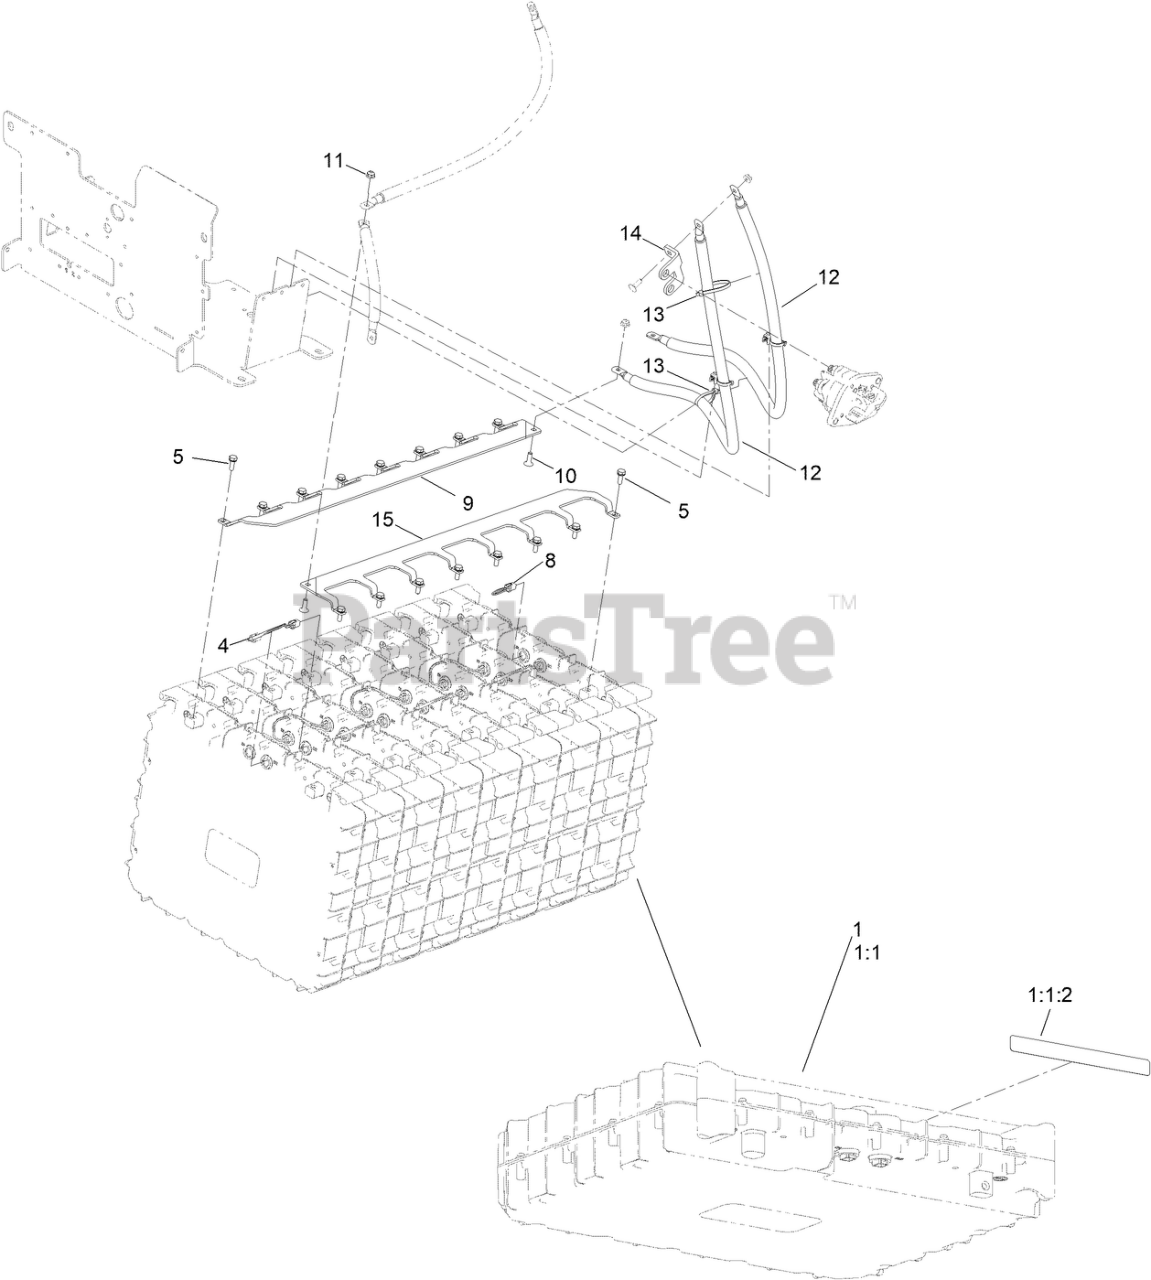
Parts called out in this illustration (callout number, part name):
1	BATTERY ASM
1:1	BATTERY ASM
1:1:2	DECAL-WARNING, BATTERY
4	HARNESS-WIRE, DATA INTERFACE
5	SCREW-SEMS
8	HARNESS-WIRE, CAN TERMINATOR
9	BUSBAR-8, RD
10	BOLT-CARR
11	NUT-HF
12	CABLE-BATTERY,RD ASM
13	TIE-CABLE
14	BUSBAR-2, SWITCH
15	BUSBAR-8, BK
